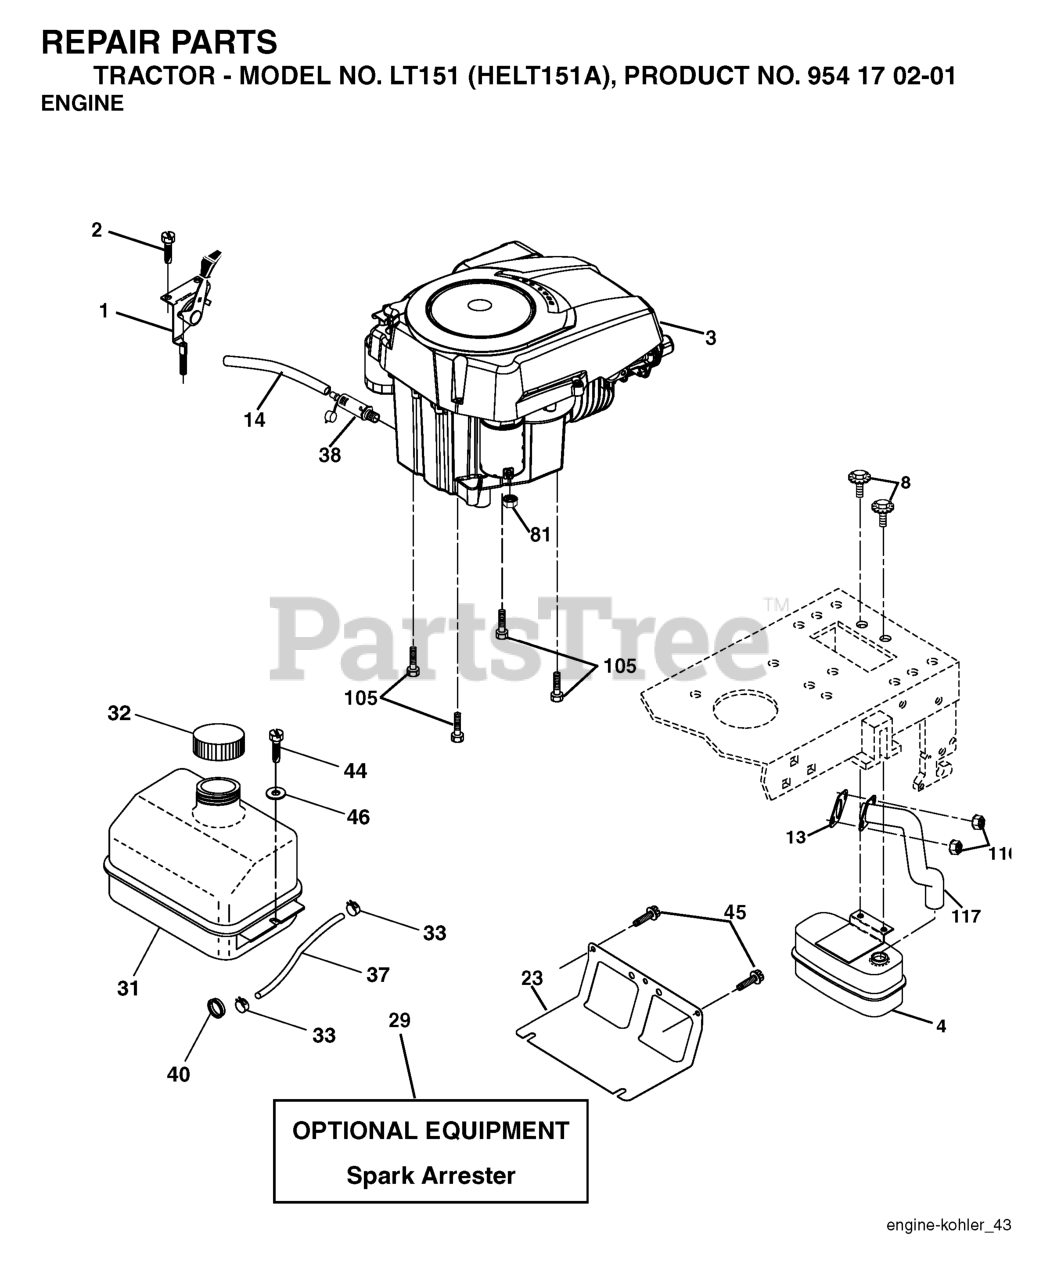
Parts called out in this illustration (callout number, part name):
1	CONTROL.THROTTLE.LT/YT
2	SCREW
4	MUFFLER.SINGLE.CYL.KOHL/B&S
8	BOLT.5/16-18UNCX3/4 W/SEMS.BLK
13	GASKET.EXHAUST.KOHLER
14	TUBE, DRAIN OIL ASM.
23	SHIELD.BROWNING.DBR.GUARD
29	KIT.SPARK ARRESTOR 794945 B&S
31	TANK.ASM.FUEL.FRONT.W/CAP
32	FUEL CAP
33	HOSE CLAMP
37	LINE.FUEL.20
38	PLUG DRAIN OIL EASY
40	BUSHING.SNAP.NYL.BLK.
44	SCREW HEXWSHR 1/4-20X3/4
45	SCREW, 3/8-16X3/4
81	NUT
105	SCREW 3/8-16X1
116	NUT.HEX.FLANGE.TOPLOCK
117	RP.TUBE.EXHAUST.KOHL.COURAGE
